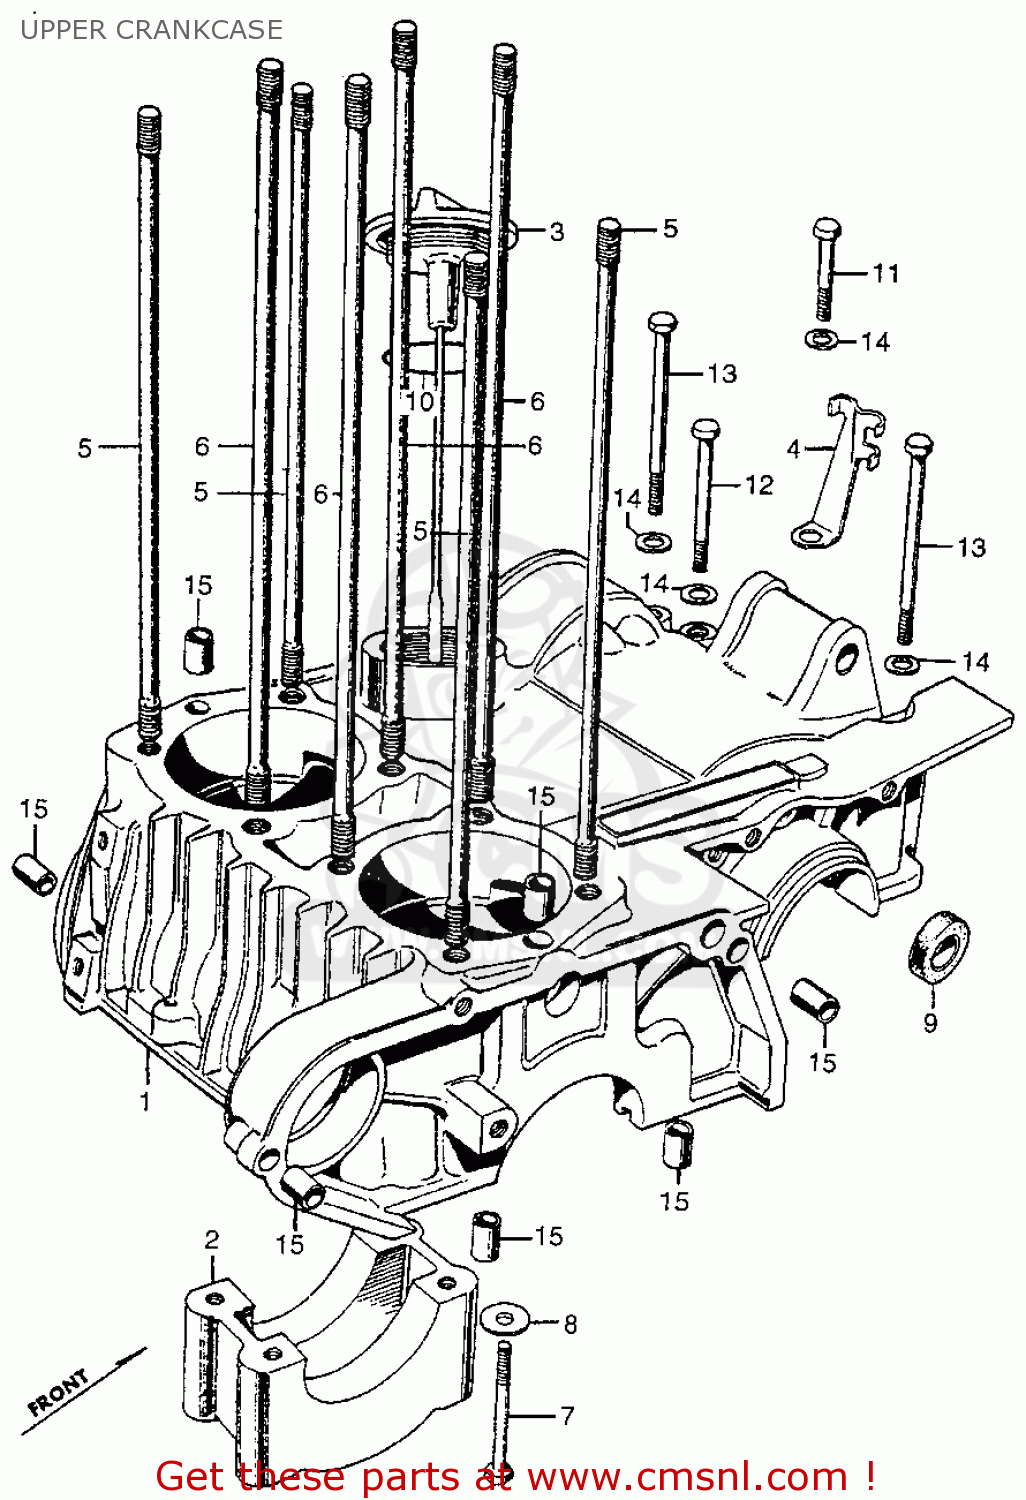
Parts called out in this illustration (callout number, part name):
1	CRANKCASE,UPPER
2	BEARINGCAP,CENTER
3	GAUGE,OIL LEVEL
4	CLAMPER, DYNAMO CORD
5	BOLT,CYLINDERSTUD
6	BOLT,CYLINDERSTUD
7	BOLT,HEX 8X71
8	WASHER,HEAD,8MM
9	OIL SEAL,12X25X45
10	O-RING,37X2.4
11	BOLT,HEX 6X40
12	BOLT,HEX 6X63
13	BOLT,HEX 6X80
14	WASHER PLAIN 6MM
15	DOWEL PIN
